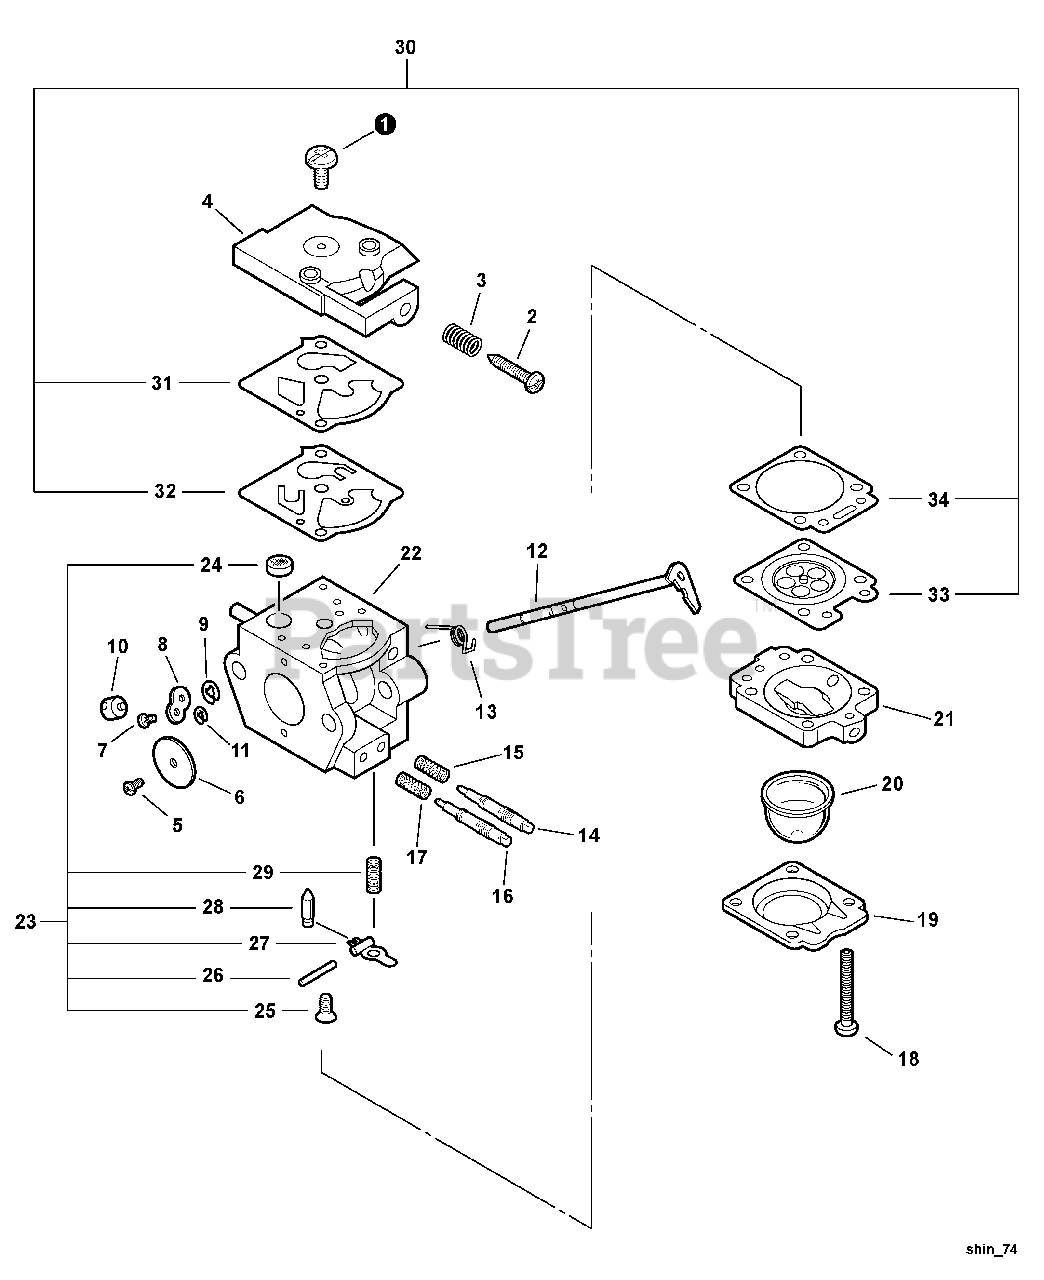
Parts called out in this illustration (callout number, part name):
1	SCREW
2	SCREW, IDLE ADJUST
3	SPRING, IDLE ADJUST
4	PUMP COVER ASSY
5	SCREW
6	VALVE, THROTTLE
8	LEVER, THROTTLE
9	RING, RETAINING
10	SWIVEL
11	E-RING
13	SPRING, THROTTLE RETURN
14	NEEDLE, LOW SPEED
15	SPRING, NEEDLE
16	NEEDLE, HIGH SPEED
17	SPRING, NEEDLE
19	RETAINER, PURGE BULB
20	BULB, PURGE
21	PURGE BASE ASSY
22	BODY, CARBURETOR
23	REPAIR KIT
24	SCREEN, FUEL INLET
25	SCREW, METERING LEVER PIN
26	PIN, METERING LEVER
27	LEVER, METERING
28	VALVE, INLET NEEDLE
29	SPRING, METERING LEVER
30	DIAPHRAGM/GASKET KIT
31	DIAPHRAGM, PUMP
32	GASKET, PUMP
33	DIAPHRAGM, METERING
34	GASKET, METERING
